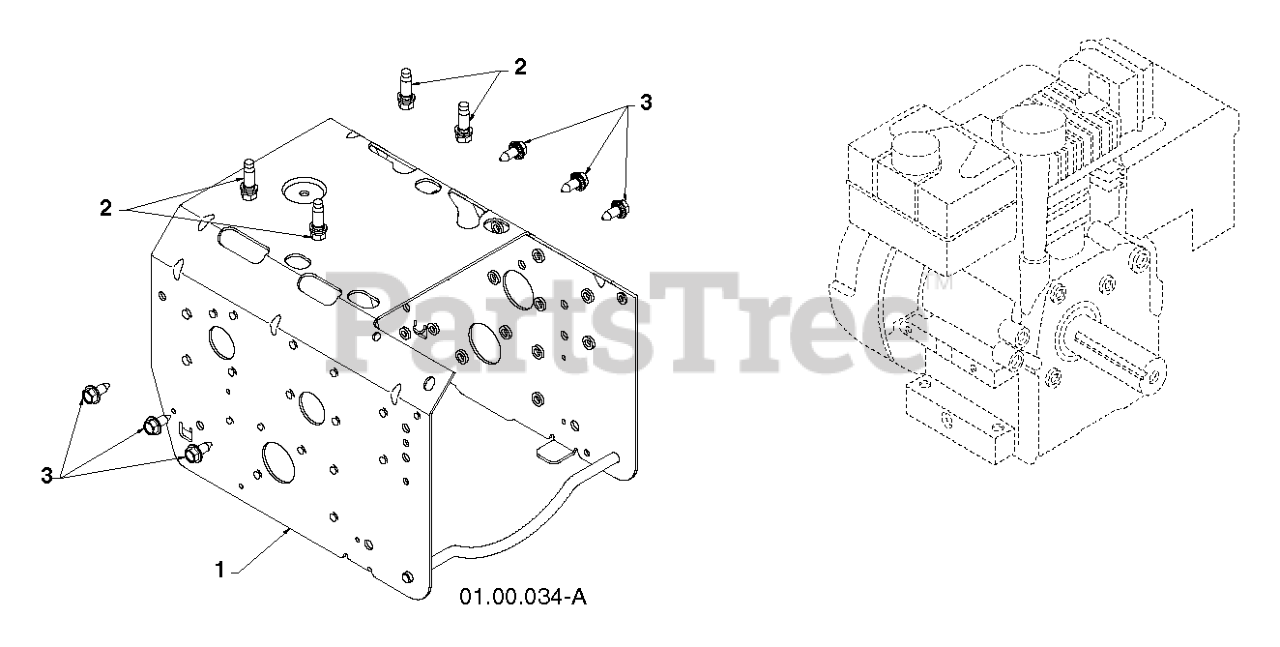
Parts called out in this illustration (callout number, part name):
1	FRAME.WELD.PNT.GEAR.ORANGE
2	BOLT 3/8-16X1-1/8
3	BOLT.HEX.HD.WASHER.5/16-18X.75
